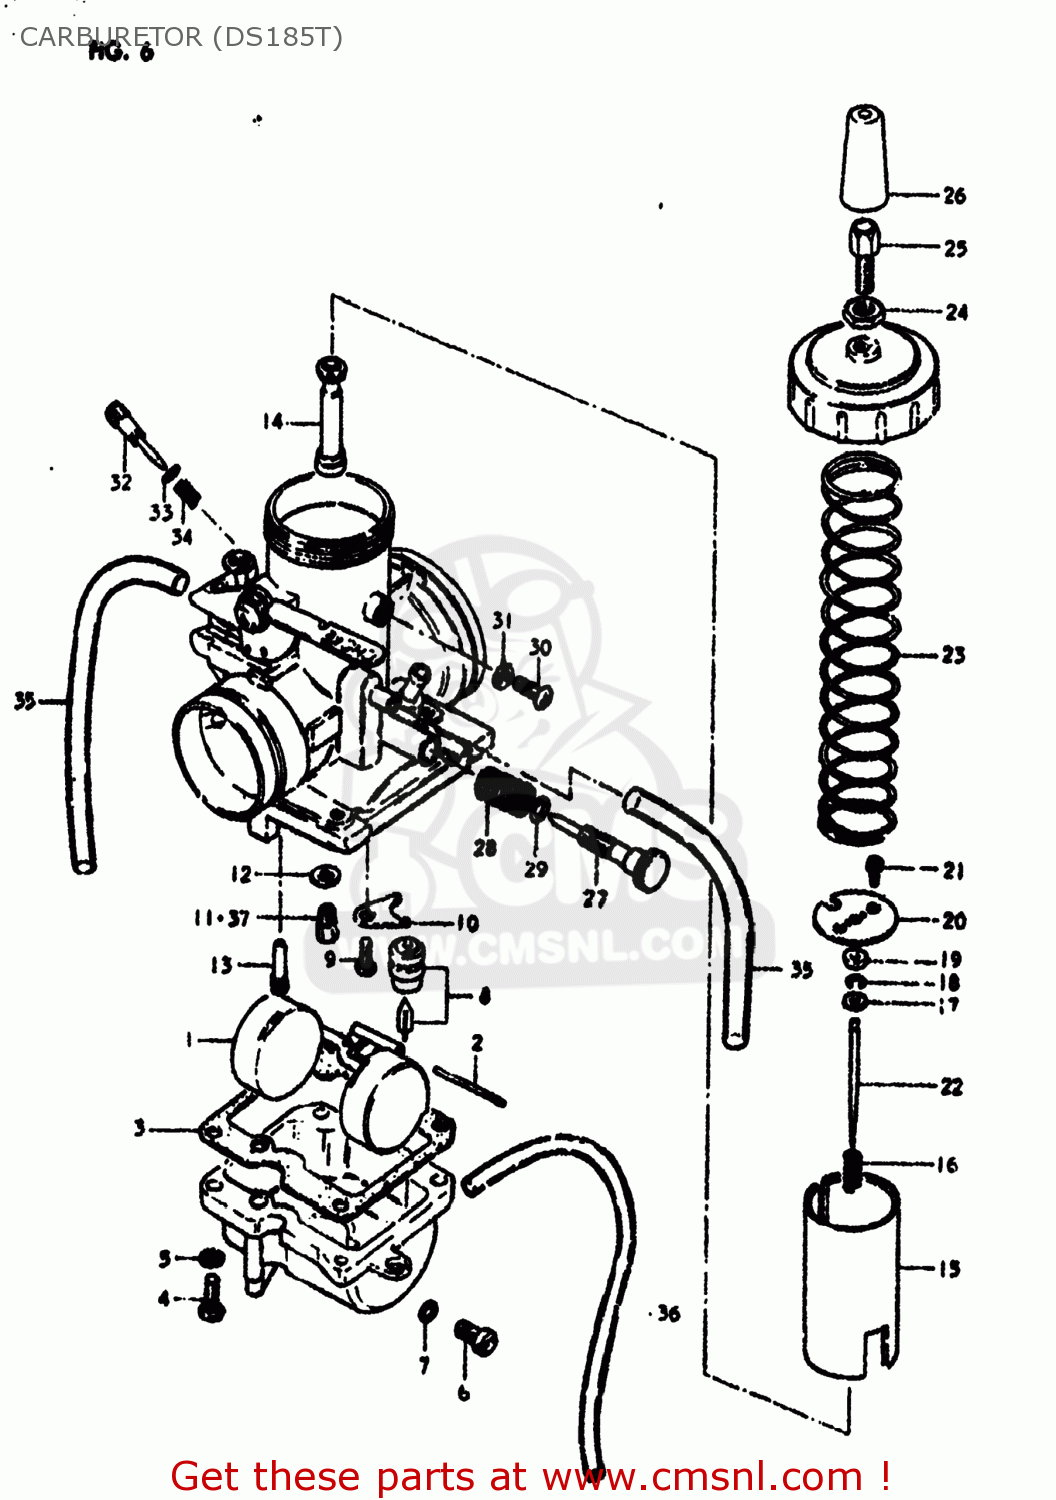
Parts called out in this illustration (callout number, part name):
1	FLOAT
2	PIN,FLOAT
3	GASKET,FLOAT CAHMBER (NAS)
4	SCREW
5	LOCK WASHER
6	PLUG
7	GASKET,DRAIN,PLUG (NAS)
8	VALVE ASSEMBLY,NEEDLE
9	SCREW
10	PLATE
11	JET
12	WASHER
13	JET
14	JET,NEEDLE
15	VALVE,THROTTLE
16	SPRING
17	WASHER,JET NEEDLE
18	CLIP
19	RING
20	PLATE
21	SCREW
22	NEEDLE,JET
23	SPRING, THROTTLE VALVE
24	NUT
25	ADJUSTER,CABLE
26	CAP
27	ADJUSTER
28	SPRING
29	O-RING
30	SCREW
31	RING
32	SCREW,PILOT AIR
33	O RING
34	SPRING
35	HOSE
36	HOSE
37	JET
